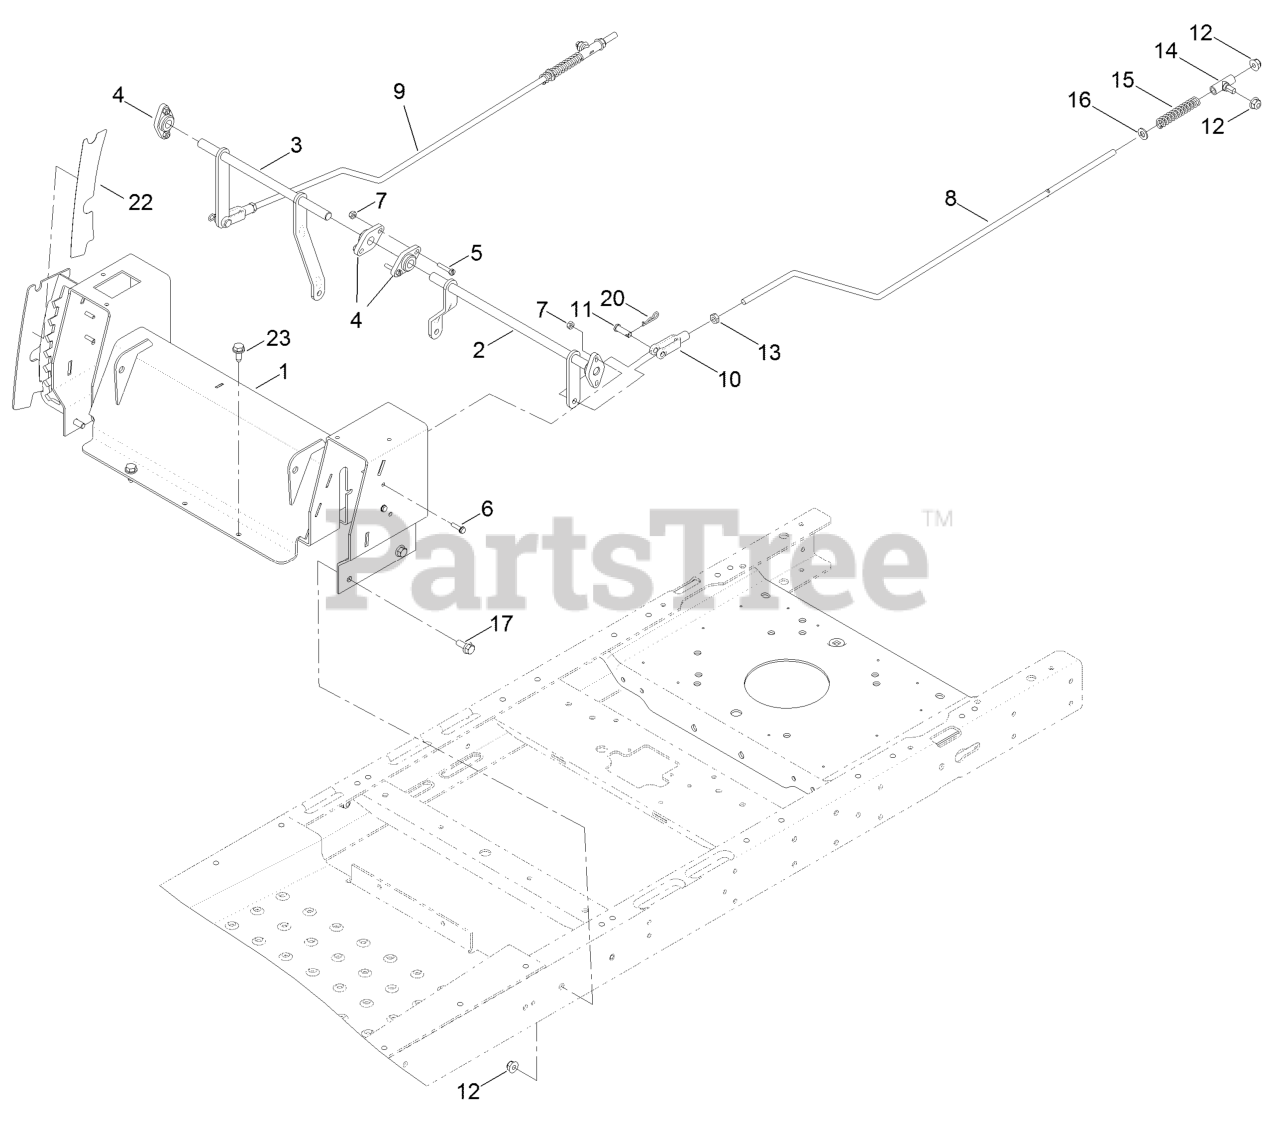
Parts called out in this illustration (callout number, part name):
1	BOX-CONTROL, WIDE
2	BELLCRANK-LH, WIDE
3	BELLCRANK-RH, WIDE
4	BEARING-FLANGE
6	SCREW-HWH
7	NUT-LOCK, NI
8	ROD-HYDRO, LH
9	ROD-HYDRO, RH
10	YOKE-ADJUSTABLE
11	PIN-CLEVIS
12	NUT-HF, NI
13	NUT-JAM
14	MOUNT-ROD, HYDRO
15	SPRING-RETURN, NEUTRAL
16	WASHER-PLAIN
17	SCREW-HHF
20	PIN-COTTER
22	DECAL-HOC
23	Screw-HWH 5/16-18 X 3/4 Tf
